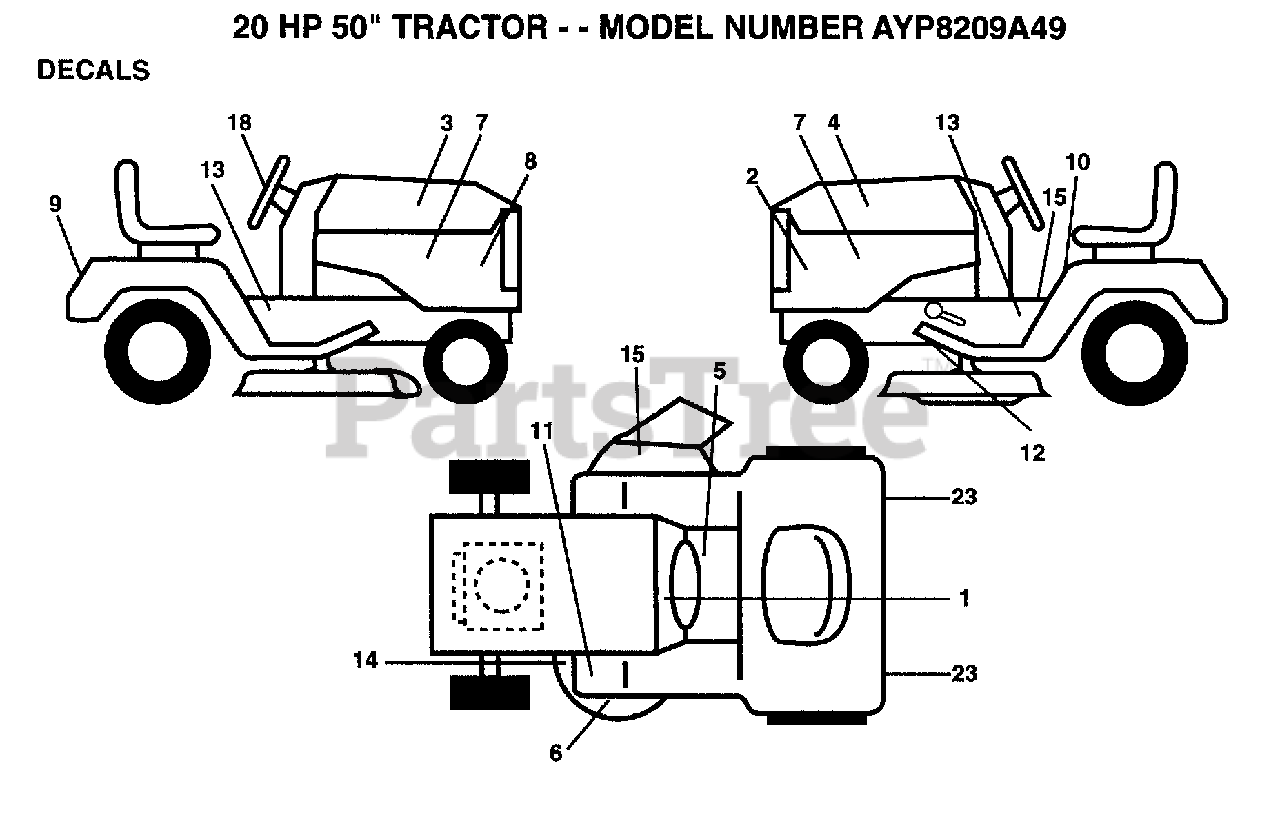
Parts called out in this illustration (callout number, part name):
1	DECAL.DASH.INST.
3	DECAL HD RH WIZ +
4	DECAL HD LH WIZ +
5	DECAL BRAK PARK
6	DECAL DECK WIZ +
7	DECAL PNL SD KOH
8	DECAL SADLE HYDRO
10	DECAL
12	DECAL D-BAR CNTRL
13	DECAL CHASSIS 50
14	"DECAL.V.BELT.44"""
15	"DECAL, WARNING"
18	DECAL INS STG WHL
23	REFLECTOR-TAIL YT
